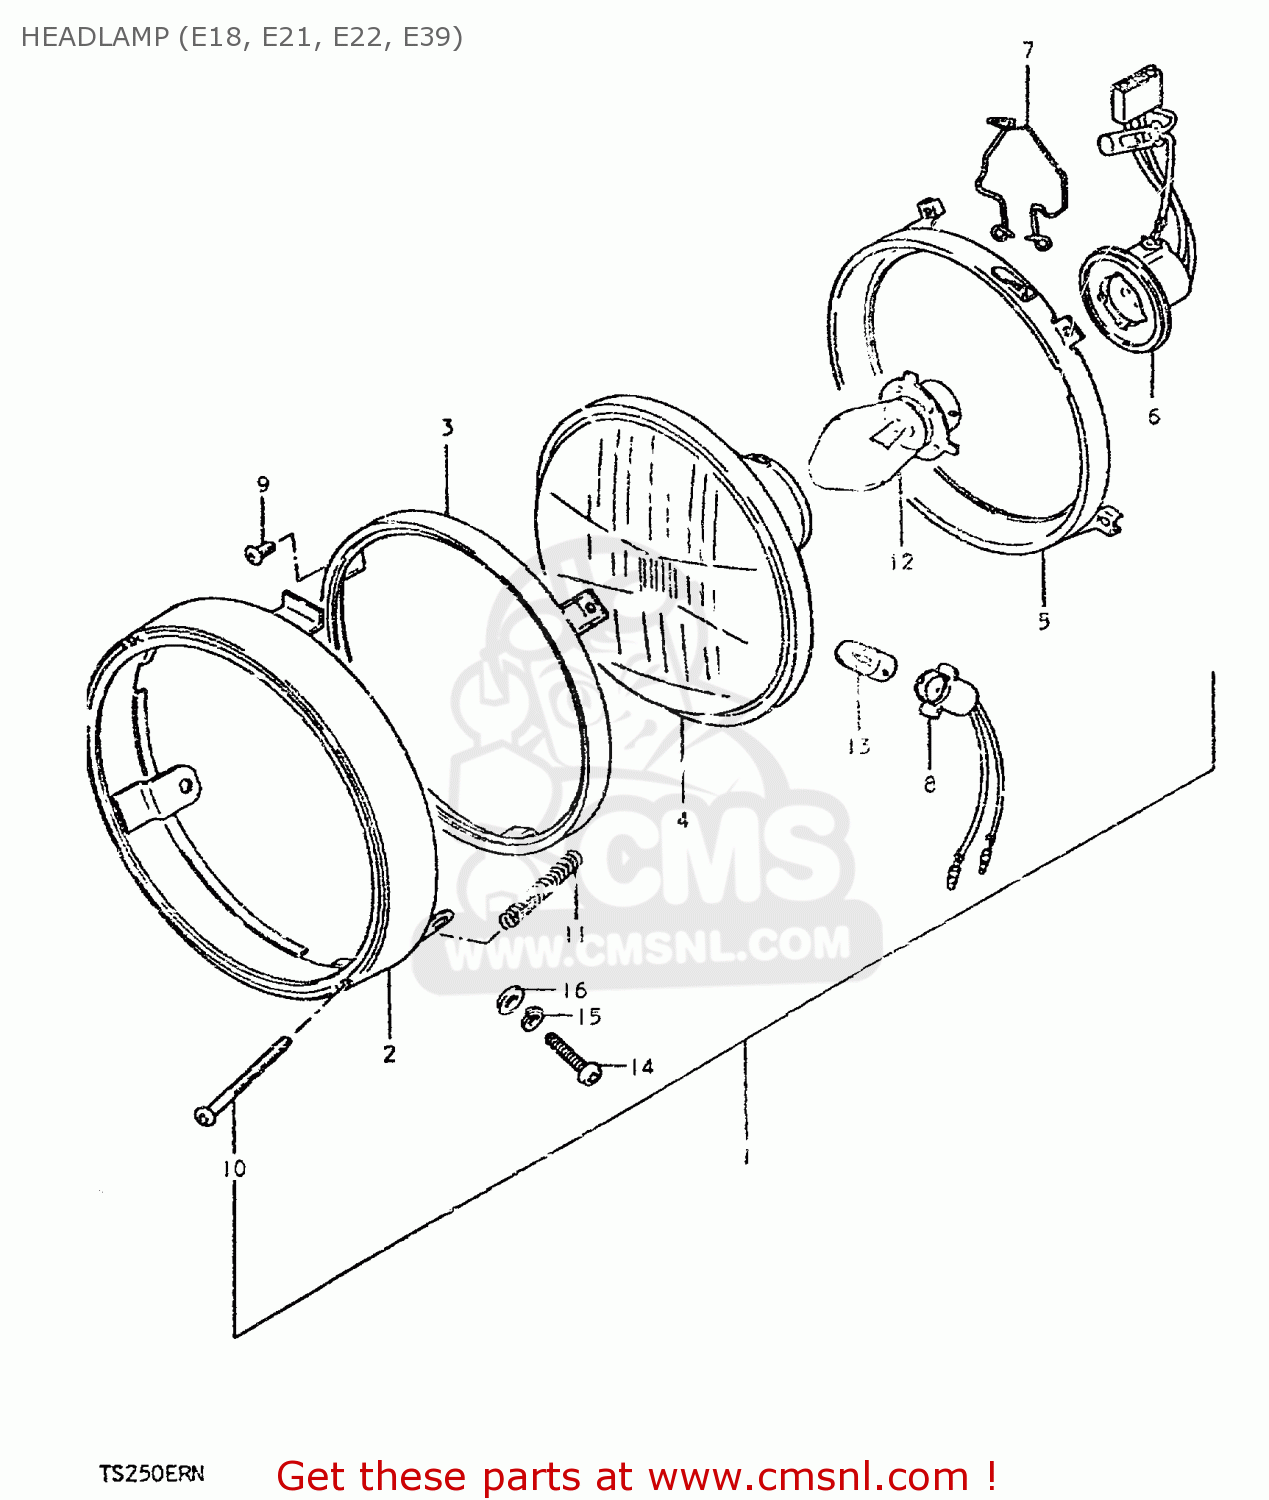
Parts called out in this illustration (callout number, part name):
1	HEADLAMP ASSY
2	RIM
3	RETAINER,HEADLAMP
4	UNIT
5	RING, MOUNTING
6	SOCKET
7	CLAMP,HEADLAMP
8	SOCKET
9	SCREW
10	SCREW,HEADLAMP ADJUST
11	SPRING,ADJUSTING
12	BULB (6V,25/25W)
13	BULB (6V,4W)
14	SCREW
15	LOCK WASHER
16	WASHER
